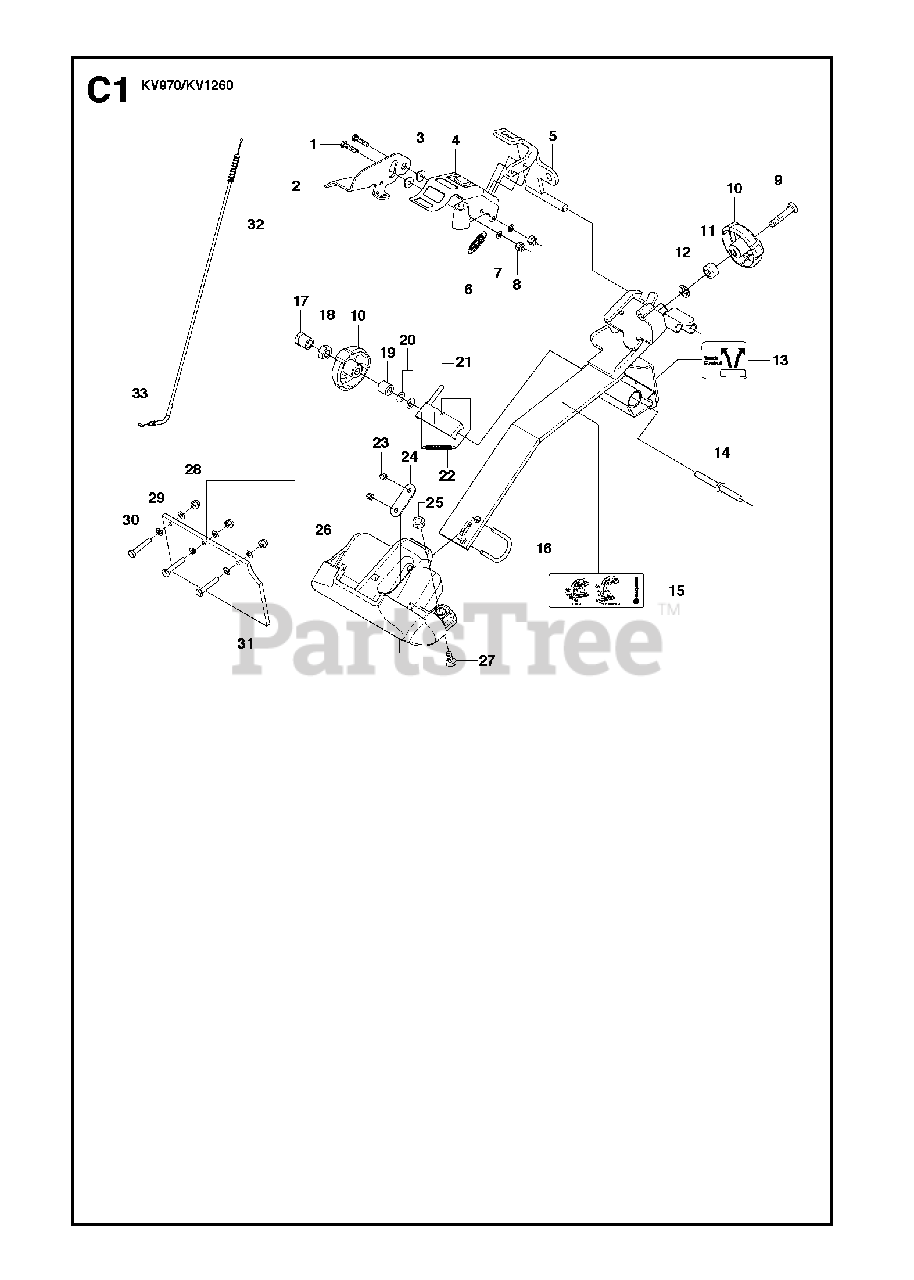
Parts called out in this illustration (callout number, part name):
7	WASHER
8	HEXAGON LOCKING NUT
10	TURNING KNOB
18	HEXAGON NUT
19	SPACING SLEEVE
23	HEXAGON LOCKING NUT
25	HEXAGON NUT
28	HEXAGON LOCKING NUT
